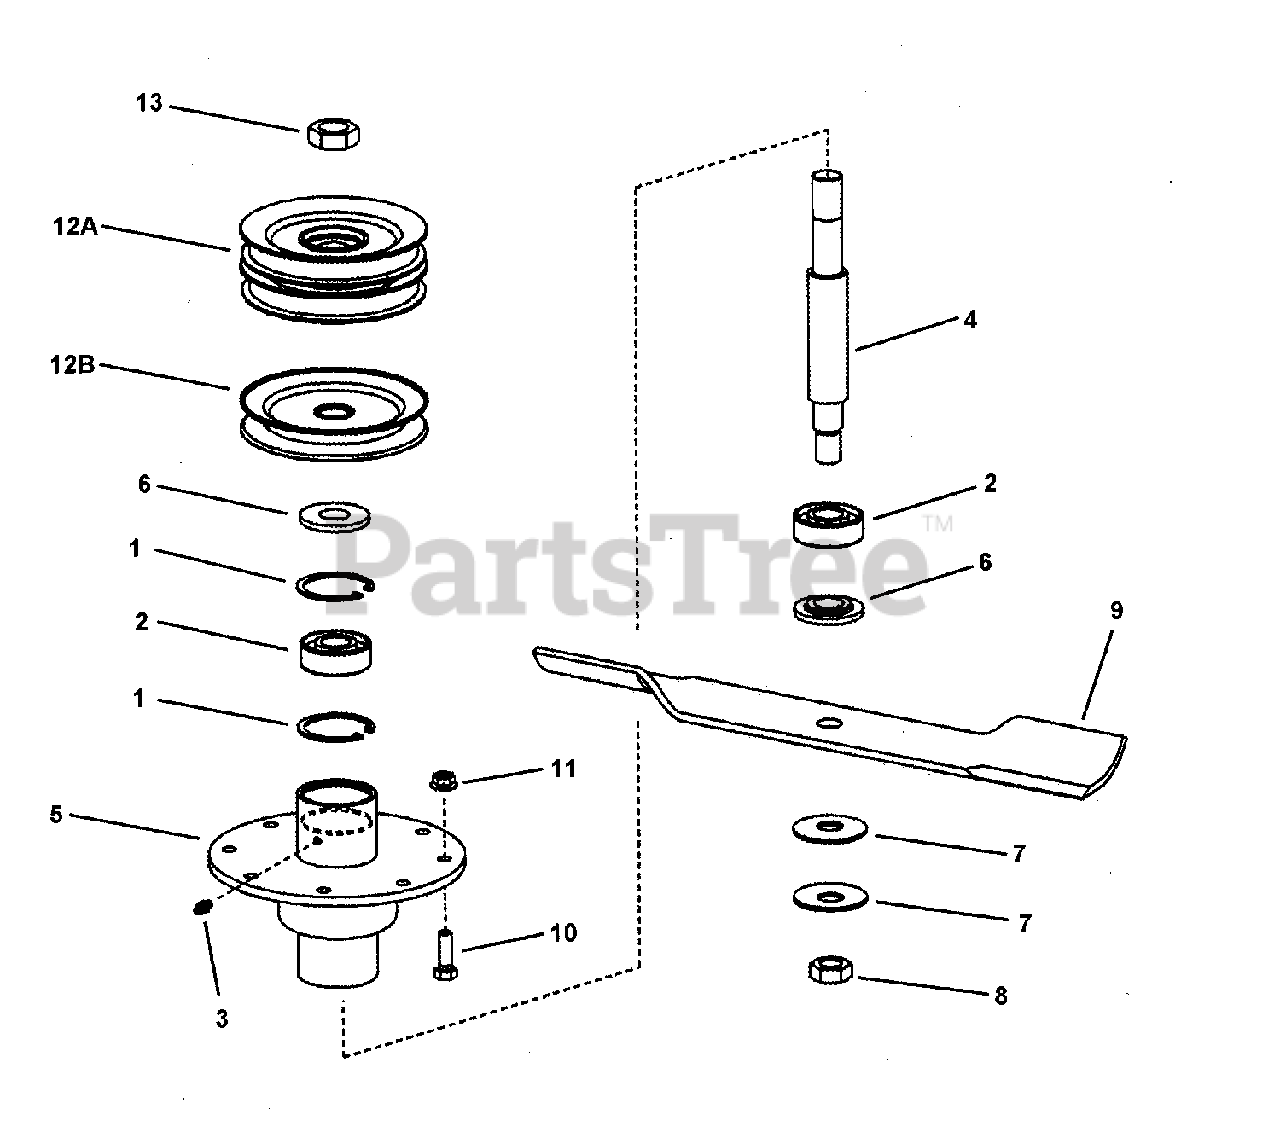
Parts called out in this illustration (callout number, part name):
1	RING, 1-3/4" Retaining
2	BALL BEARING, 3/4" I.D.
3	FITTING, Lube (Press fit for .187 hole-no ball)
4	SHAFT, 48" Spindle (7.8" long)
5	WELDMENT, Spindle Housing
6	WASHER, Spindle
7	WASHER, Belleville
8	NUT, 5/8-18 Hex Jam
9	BLADE, 16-1/2" High Lift
10	SCREW, 5/16-18 x 1" Hex Head Cap, GR5
11	NUT, 5/16-18 Hex Flange Lock, GR5
12A	PULLEY, Deck/Drive- 48" (center spindle)
12B	PULLEY, 4-3/4" O.D. (outboard spindles)
13	NUT, 3/4-16 Hex Flange Jam, GR8
